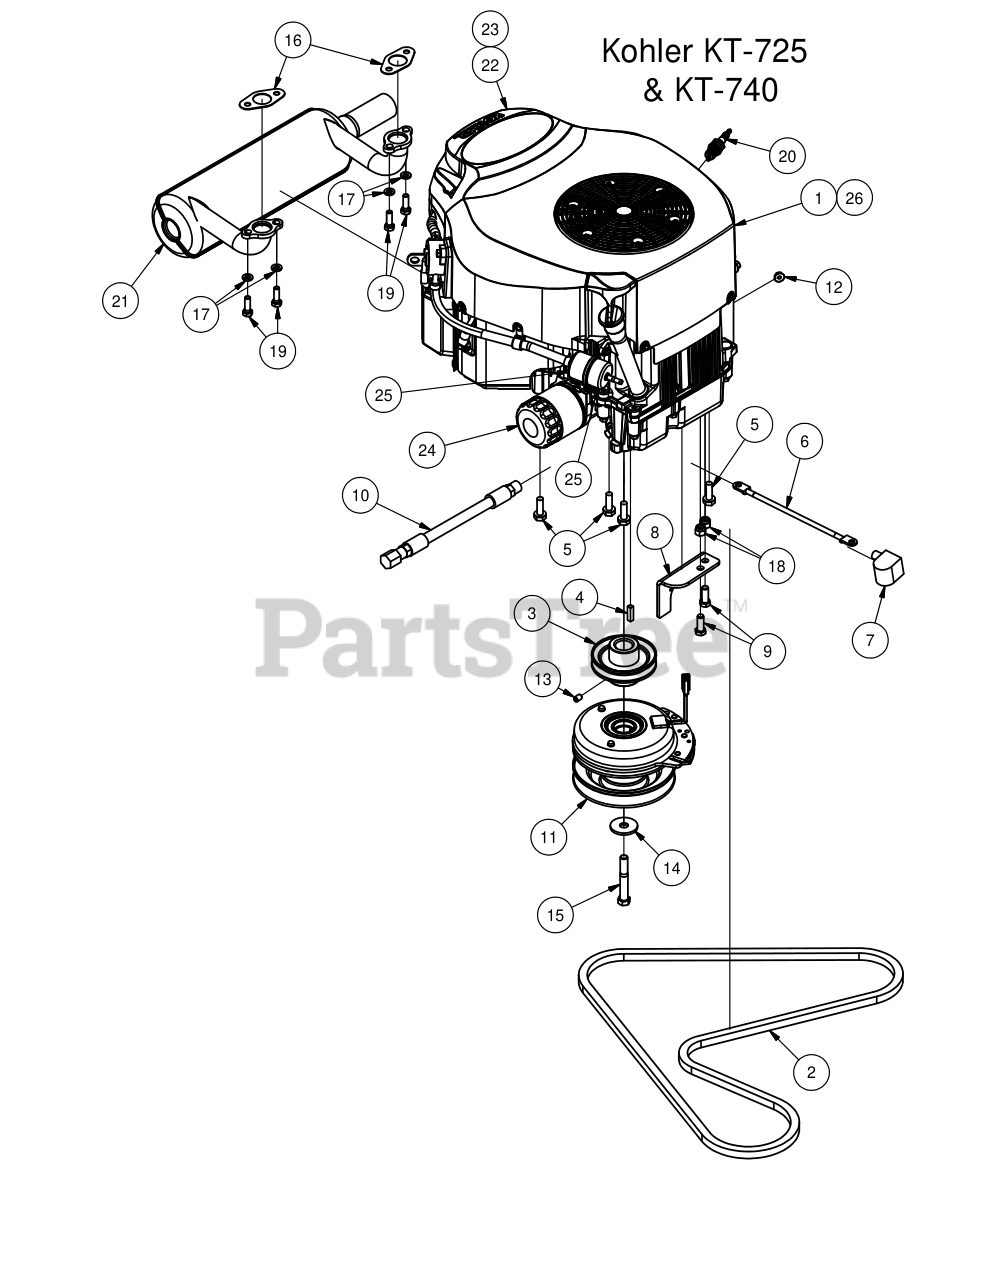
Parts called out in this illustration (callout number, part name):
1	Kohler MZ Magnum 740cc
3	3-3/4" Motor Pulley
4	1/4" x 1" Key
5	3/8 x 1 1/8 bolt
6	Ground Cable
7	Black Boot For Ground Cable
8	2017 MZ Clutch Stop
9	3/8" x 1" Hex Bolt
10	Oil drain Hose
11	Clutch 2017 Magnum/MZ
12	1/4-20 Hex Flange Nuts Zinc w/Serrations
13	3/8" Set Screw
14	1/2 Belleville Washer
15	7/16"-20 x 3" Hex Bolt Gr. 8
16	Exhaust Gasket
17	5/16" Lock Washer
18	3/8 Nylock Nut
19	5/16" x 1" Bolt
20	Spark Plug
21	Kohler Muffler
22	KT 725 & KT-740 Precleaner
23	KT 725 & KT-740 Air Element
24	KT 725 & KT-740 Oil Filter
25	Universal Fuel Filter
26	Kohler KT-725
